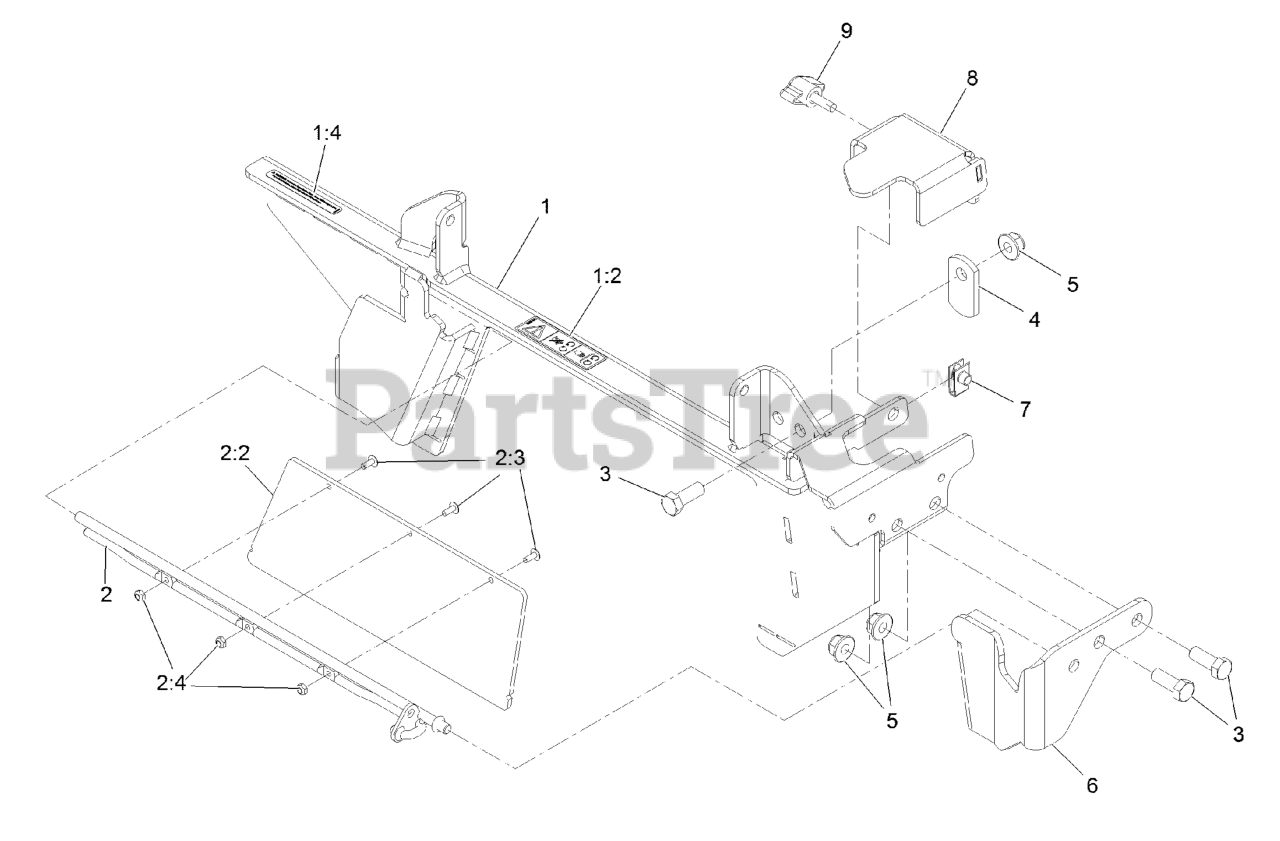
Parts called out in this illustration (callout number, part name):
1	OCD FRAME ASM W/ DECALS
1:2	DECAL, COVER MISSING
1:4	DECAL-WARNING
2	OCD GATE ASM
2:2	GATE-OCD
2:3	SCREW-PTH
2:4	NUT-LOCK, NI
3	SCREW-HH
4	LATCH-CATCHER, GRASS
5	NUT-HF, NI
6	BRKT,CHUTE FRONT
8	BRACKET, CABLE MOUNT
